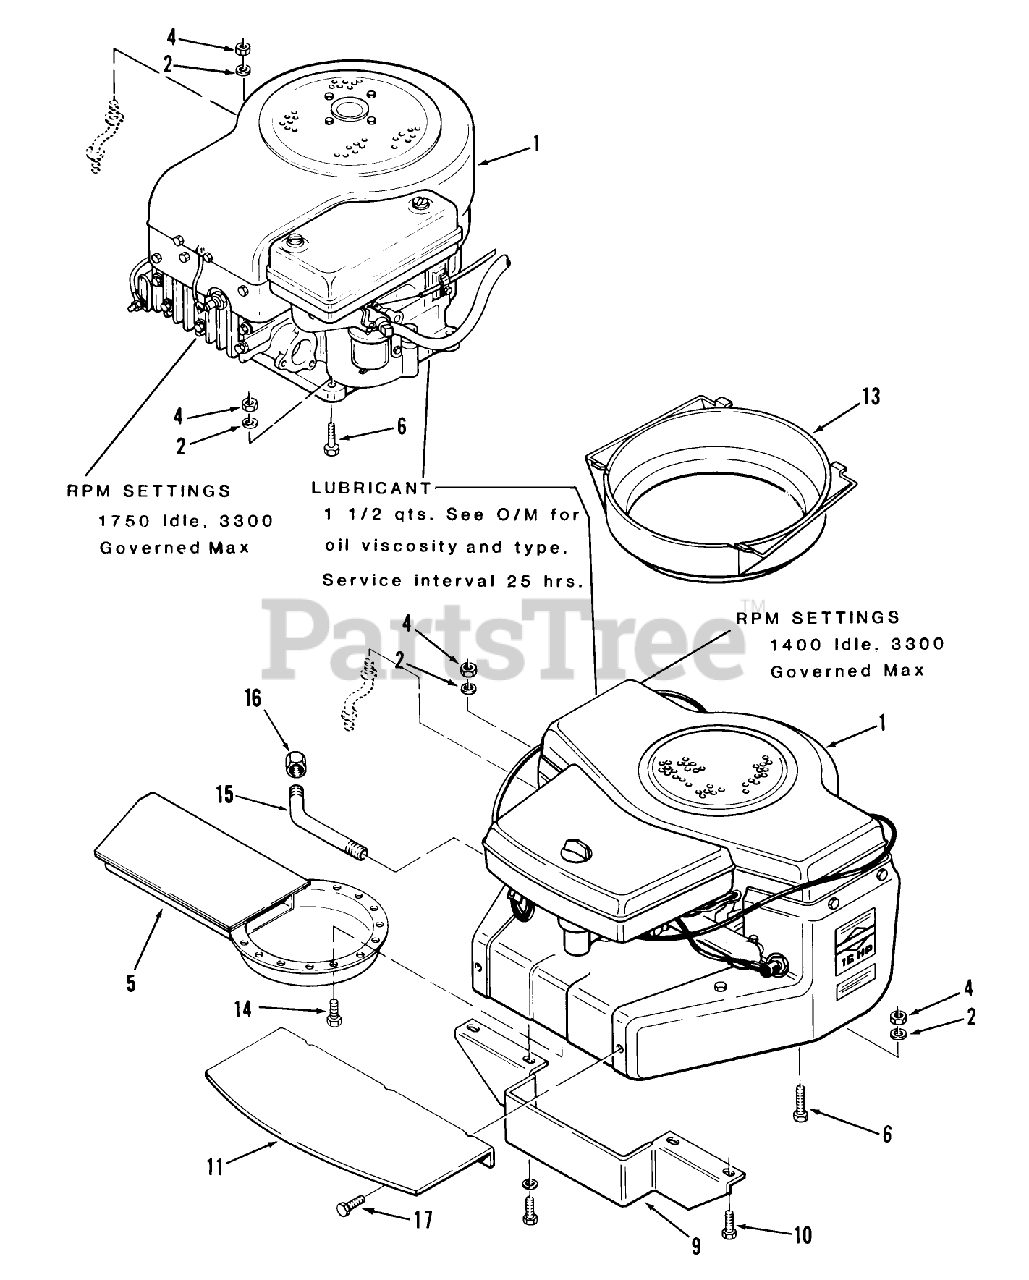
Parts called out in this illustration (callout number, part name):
1	Engine-11HP-BS Model 252707, Type 0222-02
1	Engine-16HP-BS Model 402707, Type 0130-03, LT-1637 Only
2	WASHER 5/16 SAE
13	DUCT-AIR INTAKE
